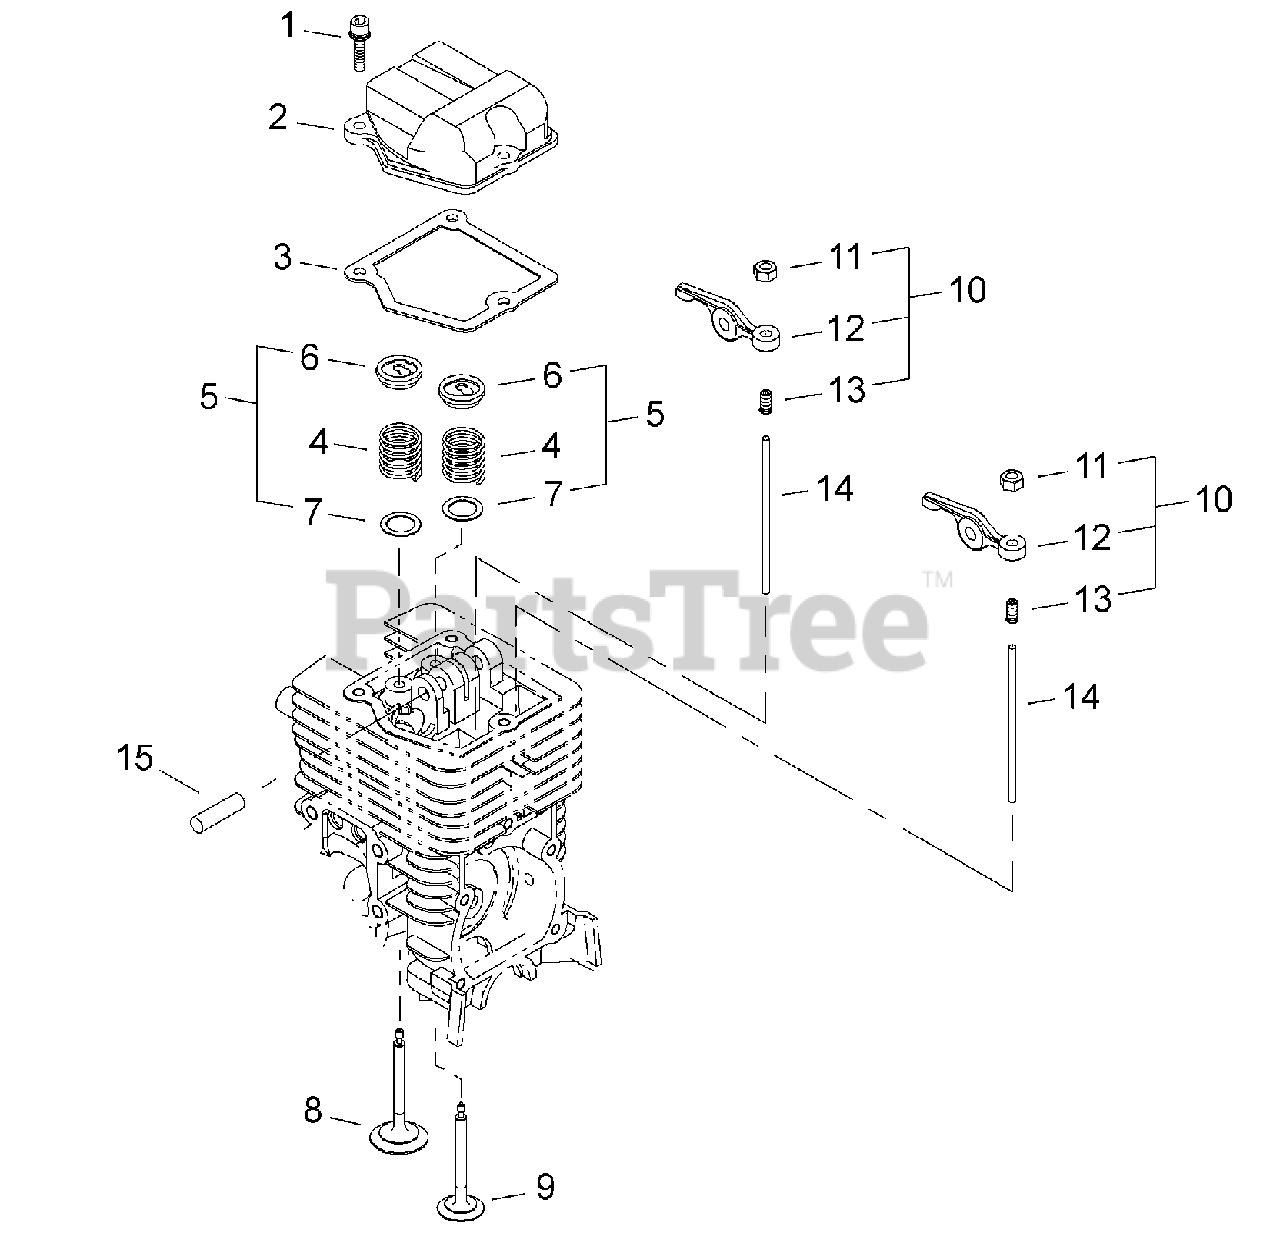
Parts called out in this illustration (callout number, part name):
1	BOLT M4×12
2	COVER, ROCKER ARM
3	GASKET, ROCKER ARM
4	SPRING, VALVE
5	RETAINER SET, VALVE
6	RETAINER, VALVE
7	WASHER, VALVE 9
8	VALVE, INTAKE
9	VALVE, EXHAUST
10	ARM ASSY, ROCKER
11	NUT, ADJUSTER LOCK 5
12	ARM, ROCKER
13	SCREW, ADJUSTER
14	PUSHROD
15	SHAFT, ROCKER ARM Ø5×31.8 MM
